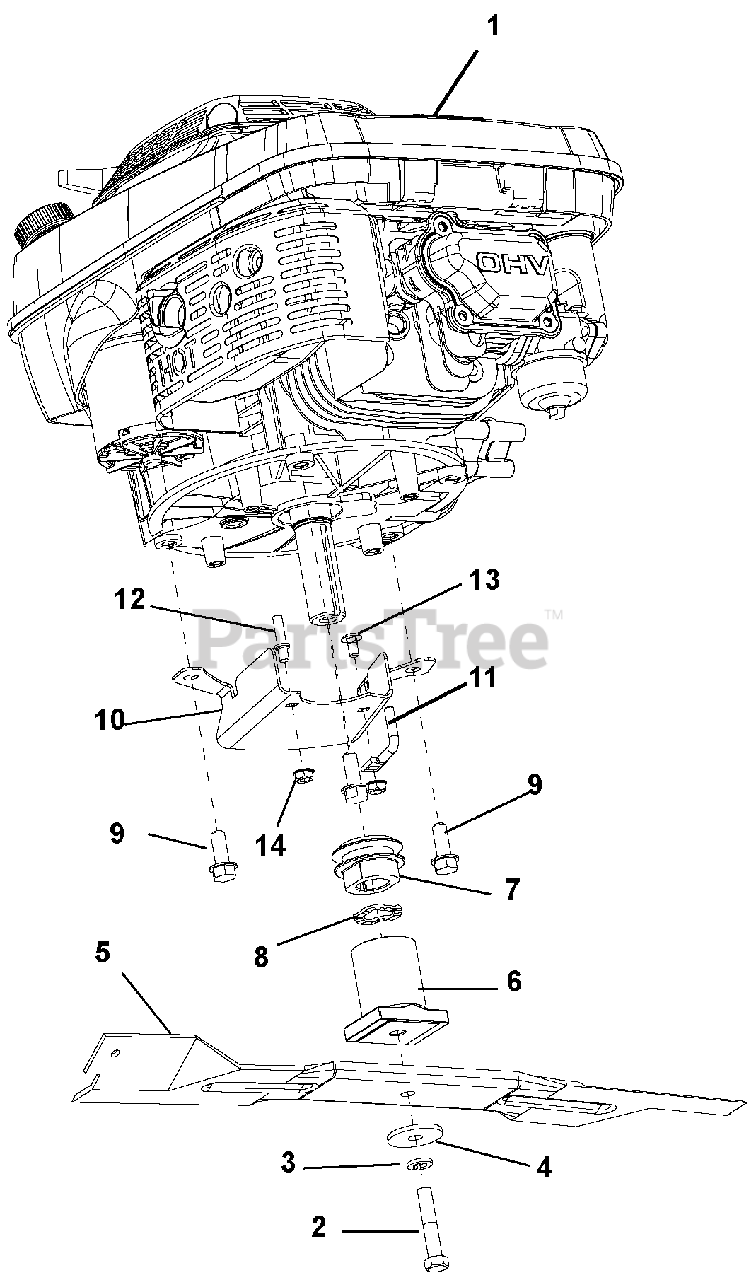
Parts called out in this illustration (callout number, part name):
1	ENGINE, KAWI 6.0 COMM 2006
2	BLT-HEX .38-24 X 2.00 GR8 YWZC
3	@WSHR-LK .38X.094 REG YWZC
4	WSHR-FL-STL .390X1.5X.125 YWZC
5	21" MOWER BLADE
6	ADAPTER, CE BLADE
7	PULLEY-SINTERED IRON LM
8	WASHER-WAVE .885X1.311X.125
9	@SCR-TAP .38-16X1.00 HWH TR YZ
10	GUIDE-BELT
11	FINGER, BELT
12	FINGER, BELT
13	@BLT-RDHDSQNK .25-20X.50 G5YZ
14	@NUT-SPNLK-FLG .25-20 YWZC
